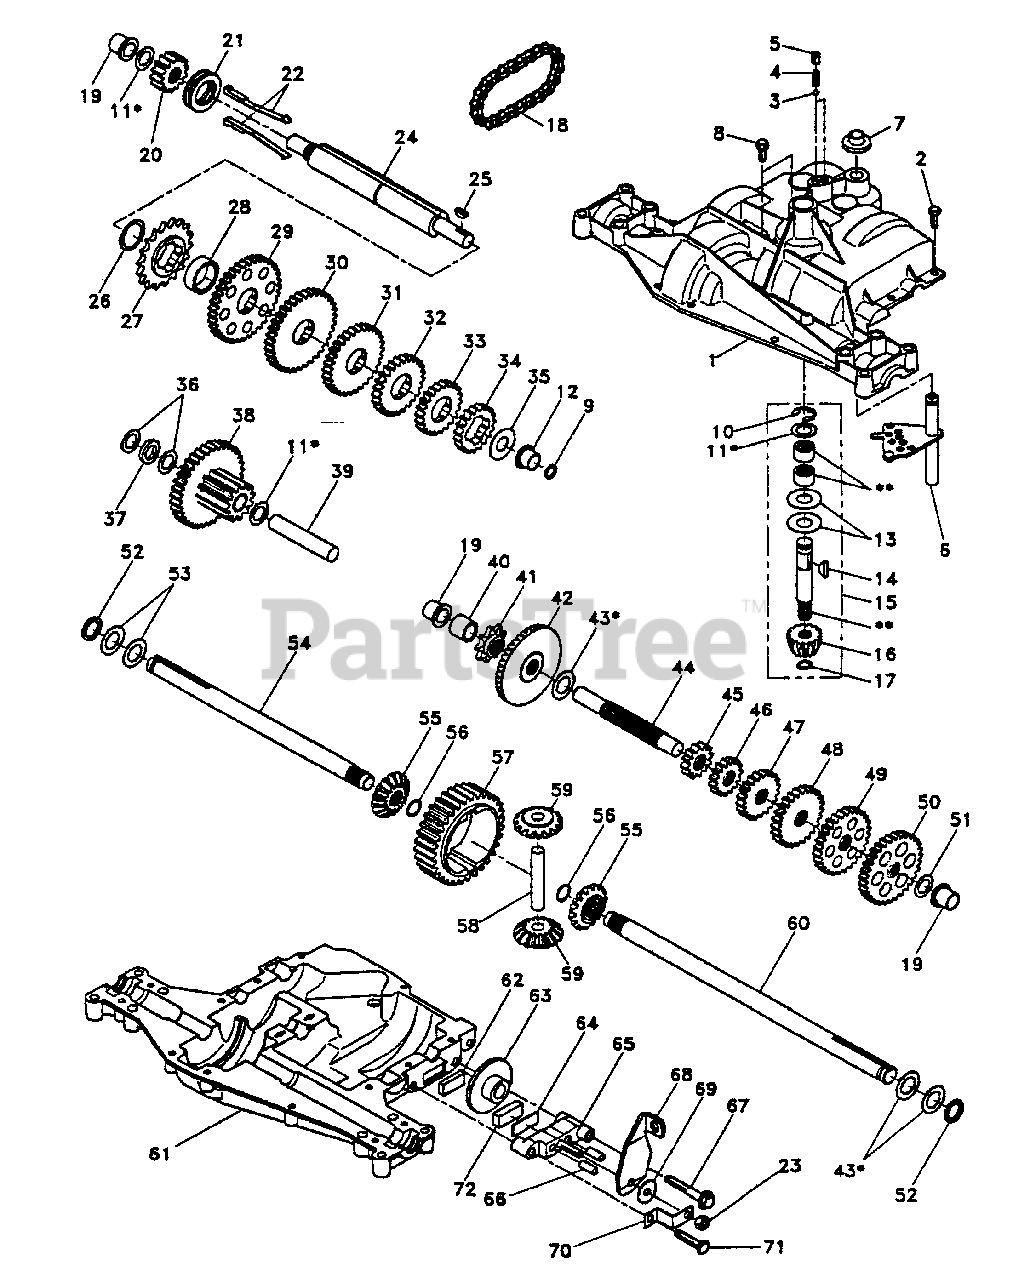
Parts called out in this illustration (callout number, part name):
1	Housing, Upper
2	Screw, Self-Tapping, Large 1/4-20 x .734
3	Ball, Detent
4	Spring, Detent
5	Screw, Set
6	Kit, Shifter Assembly
7	Boot, Shifter
8	Screw, Self-Tapping, with Sealer
9	Square Ring
10	Ring, Retaining
11	Assembly, Kit, Shim .625 Shaft
12	Bearing, Flange
13	Washer, Plain .632 x 1.38 x .046
14	Key, Woodruff, #9
15	Assembly, Kit, Input Shaft
16	Pinion, Bevel, 14 Teeth
17	Ring, Retaining
18	Chain, 24 Pitches
19	Bearing, Flange
20	Gear, Spur, 14 Teeth
21	Collar, Clutch
22	Assembly, Kit, Clutch Keys
23	Locknut 5/16-24
24	Shaft, Intermediate
25	Key, Woodruff, #61
26	Ring, Retaining
27	Sprocket, 18 Teeth (Reverse)
29	Gear, Spur, 37 Teeth (1st)
30	Gear, Spur, 35 Teeth (2nd)
31	Gear, Spur, 30 Teeth (3rd)
32	Gear, Spur, 25 Teeth (4th)
33	Gear, Spur, 22 Teeth (5th)
34	Gear, Spur, 19 Teeth (6th)
35	Washer, Plain .640 x 1.37 x .061
36	Washer, Plain .632 x 1.00 x .026
37	Spacer .630 x 1.00 x .169
38	Assembly, Gear, Combination of 12 Teeth and 35 Teeth
39	Shaft, Idler
40	Spacer .635 x .875 x .755
41	Sprocket, 9 Teeth (Reverse)
42	Gear, Bevel, 42 Teeth
43	Assembly, Kit, Shim .750 Shaft
44	Shaft, Drive
45	Gear, Spur, 12 Teeth (1st)
46	Gear, Spur, 15 Teeth (2nd)
47	Gear, Spur, 20 Teeth (3rd)
48	Gear, Spur, 25 Teeth (4th)
49	Gear, Spur, 28 Teeth (5th)
50	Gear, Spur, 31 Teeth (6th)
51	Washer, Plain .632 x 1.00 x .060
52	Washer, Neoprene
53	Washer, Plain .758 x 1.25 x .031
54	Axle, L.H.
55	Gear, Miter, 15 Teeth
56	Ring, Retaining
57	Gear, Spur, 32 Teeth
58	Shaft, Cross
59	Gear, Miter, 15 Teeth
60	Axle, R.H.
61	Housing, Lower
62	Puck, Friction
63	Disc, Brake
65	Jaw, Brake
66	Pin, Dowel
67	Screw, Self-Tapping, Large 5/16-18 x 2.25
68	Lever, Actuating
69	Washer, Plain .321 x 1.00 x .055
70	Bracket, Anti-Rotation
71	Screw, Self-Tapping, Large 5/16-18 x 1.44
72	Puck, Friction
73	Grease
